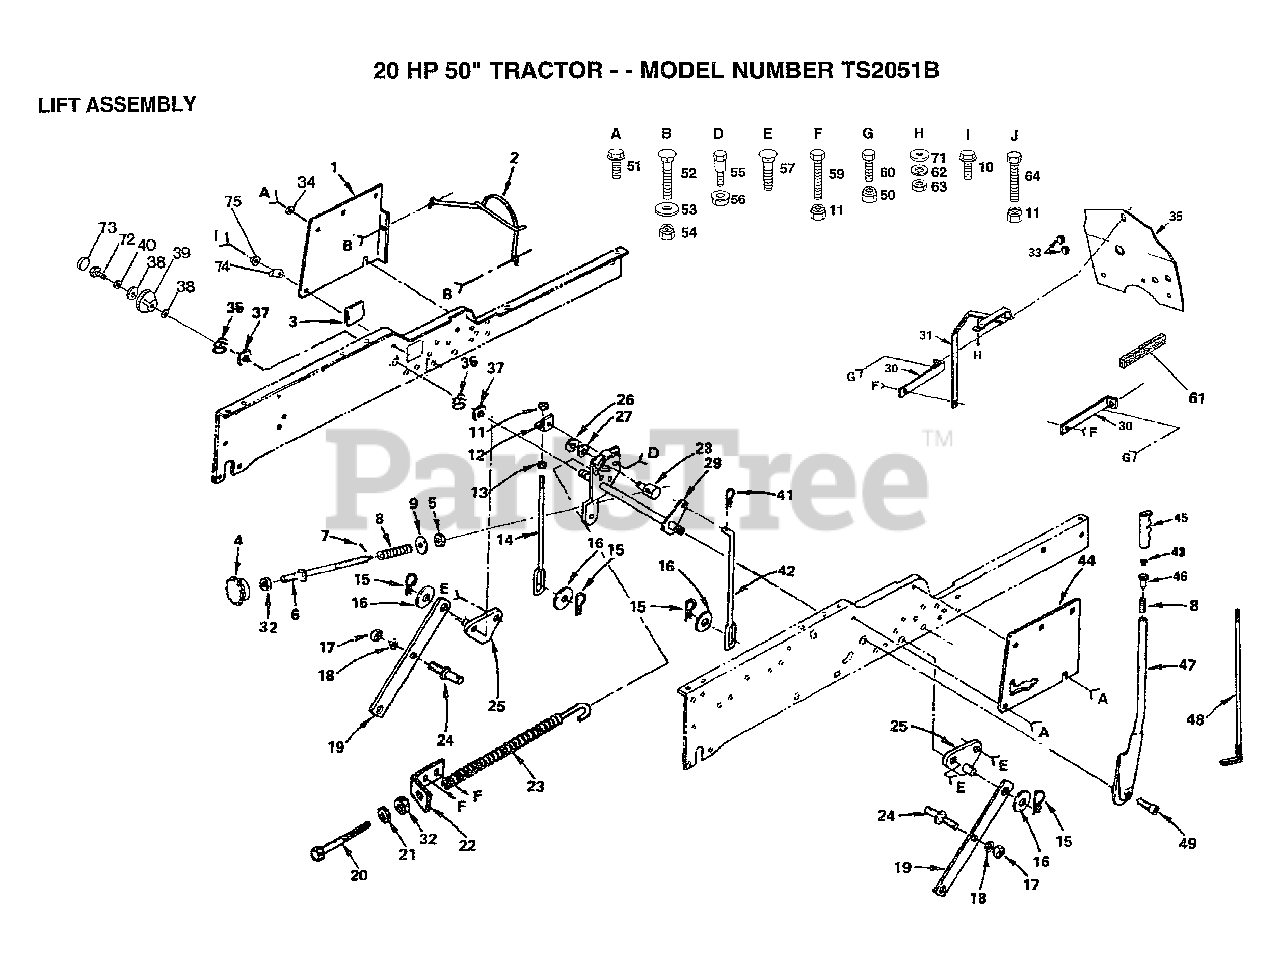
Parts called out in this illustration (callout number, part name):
2	"GUARD, BELT"
3	COVER ACCESS
4	KNOB INF 3/8-16
5	NUT T
6	ROD ADJ. T
8	SPRING T
9	WASHER
10	SCREW
11	NUT
12	BRACKET T
13	NUT.HEX.3/8-16UNC
14	LINK-LIFT MOW T
15	SPRING H
17	NUT
18	LOCKWASHER
19	SUSPENSION ARM GT
20	BOLT-ADJ SPRING T
21	WASHER
24	PIVOT STUD GT
25	SUSP BRACKET T
26	KLIP RING
27	WASHER
28	TRUNION LT
29	SHAFT ASS'Y LIFT
30	BRACKET T
32	NUT
34	LOCKWASHER
35	"SHIELD HEAT, BASE"
36	E-RING
37	WASHER
38	WASHER
39	HEIGHT INDICATOR
40	LOCKWASHER
42	LIFT LINK RH T
45	GRIP
48	LEVER ROD LT
49	"BOLT,HEX"
50	NUT
51	SCREW LT
52	BOLT
53	WASHER
54	NUT
55	SHOULDER BOLT T
56	NUT T
57	SCREW
59	BOLT
60	BOLT
61	FOAM STRIP T
71	WASHER PM
73	"PLUG,HOLE"
74	POINTER HGT IND
75	WASHER T
